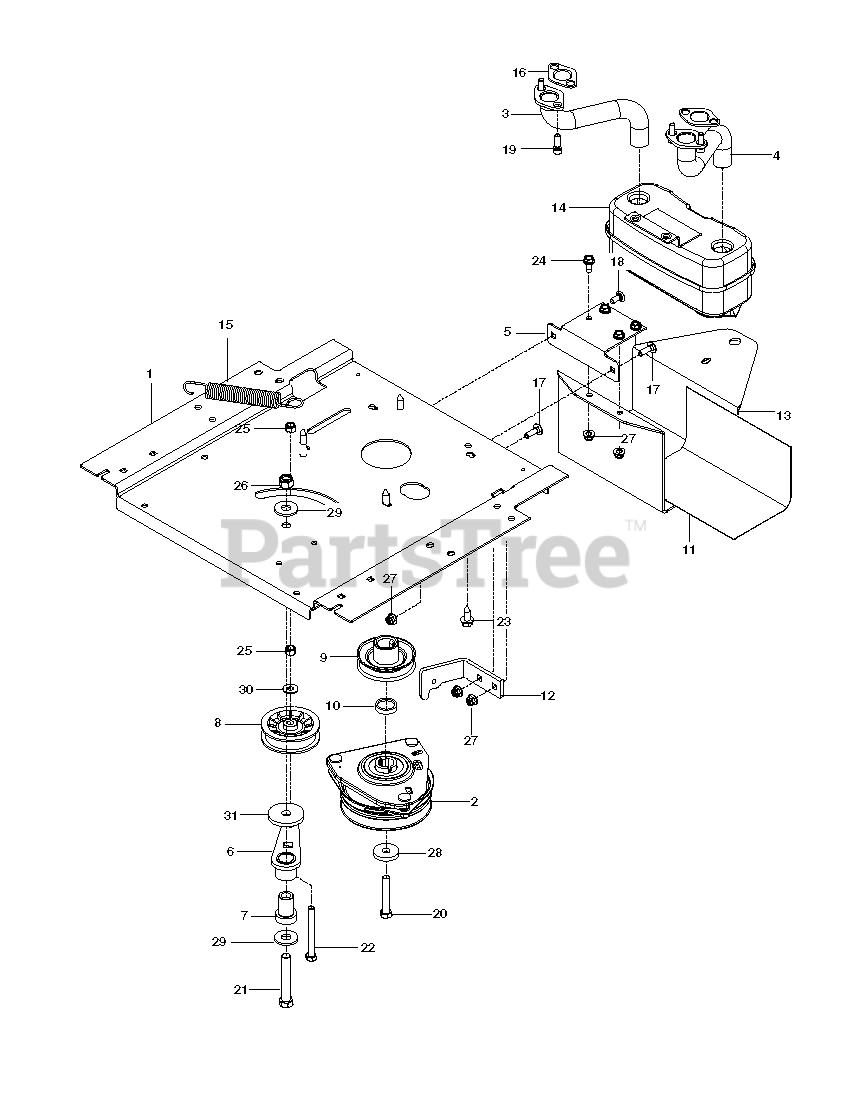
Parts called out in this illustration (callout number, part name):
1	ENGINE PLATE RZ
2	CLUTCH.ELECTRIC.LT.48"*
3	RP.EXHAUST.TUBE.LH.BS/TWIN
4	EXHAUST.TUBE.RH.BS/TWIN
5	BRACKET, MUFFLER, BLACK
6	IDLER ARM WELDMENT
7	IDLER SPINDLE
8	PULLEY, IDLER RAKE & ZTR
9	RP PULLEY, ENGINE
10	SPACER, HUB PULLEY
11	GUARD, MUFFLER, BLACK
12	CLUTCH STOP OGR BLK
13	GUARD, MUFFLER, BLACK
14	MUFFLER ASM TWIN
15	SPRING, DECK DRIVE
16	GASKET.MUFFLER
17	RHSNB 5/16C X 1
18	BOLT 5/16C X 3/4" CARRIAGE
19	SCREW.SOCKET.HEAD.5/16-18
20	HCS 7/16-20 X 2.5 GR8
21	HCS 1/2C X 3 1/4
22	HCS 3/8-16X3 1/2 GR5
23	HHFS 3/8-16 X 1.0 THD FORMING
24	HHFS 5/16-18 X 3/4
25	NUT 3/8-16 NYLOC
26	RP NUT 1/2-13 HEX NYLOC ZD
27	5/16-18 NYLOC FLANGE NUT
29	WASH USS FLAT 1/2
30	WASHER 5/16 FLAT
31	HEAVY WASHER
